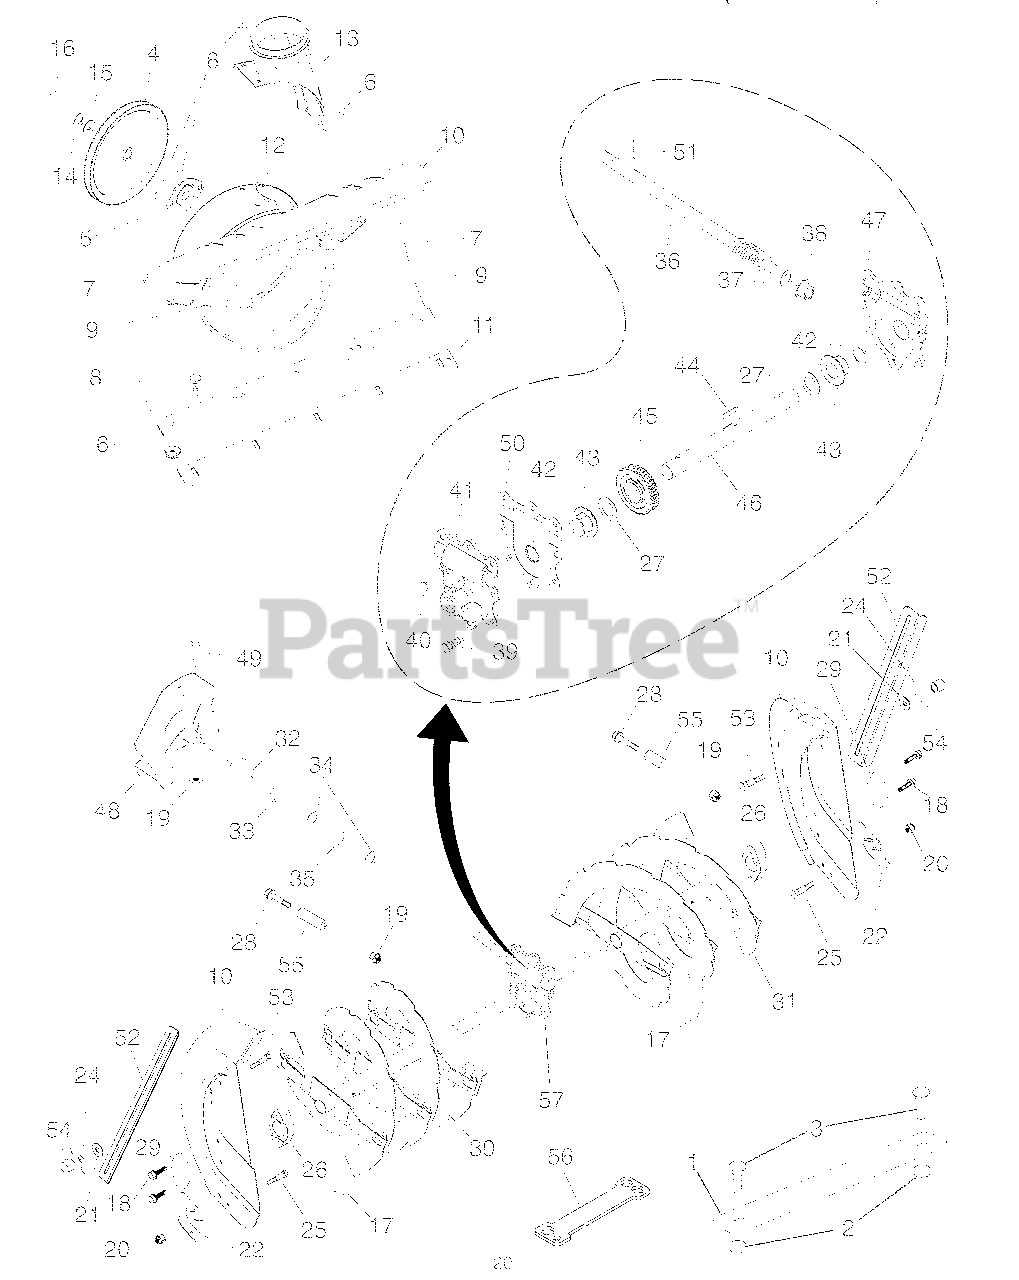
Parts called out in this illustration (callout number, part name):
1	Bar, Weight
2	Nut, Hex 5/16-18
3	Bolt, Carriage 5/16-18 x 1-1/4
4	Pulley, Impeller
5	Bearing Assembly, Flange
6	Nut, Hex Flange 5/16-18
7	Bolt, Flat Head, Carriage 5/16-18 x 5/8
8	Bolt, Carriage 5/16-1 8 x 5/8
9	Bolt
10	Housing, Auger
11	Bar, Scraper
12	Bracket, Corner Discharge
13	Base, Discharge Chute
14	Washer, Lock 5/16
15	Washer, Flat
16	Screw, Hex Head 5/16-18 x 3/4
17	Grease Fitting
18	Screw, Hex Head 5/16 x 1
19	Nut, Hex Lock 1/4-20
20	Nut, Hex Lock 5/16-18
21	Washer, Flat 5/16
22	Skid Plate, Heavy Duty
25	Bolt, Shoulder 1/4-20
26	Bearing Retainer, Plastic
27	Washer, Thrust, 1"
28	Bolt, Shear
30	Auger Assembly, RH
31	Auger Assembly, LH
33	Bushing, Flange 3/4
34	Washer, Thrust 3/4
35	Bearing, Thrust 3/4
36	Shaft, Impeller
37	Washer, Thrust 5/8
38	Bushing, Flange 5/8
39	Screw, Hex Head 5/16-18 x 3/4
40	Plug, Case
41	Housing, Gearbox, RH
42	Seal, Oil
43	Bushing, Flange, 1"
44	Key, Square 1/4 x 1/4 x 7/8
45	Gear, Worm
46	Shaft, Auger
47	Housing, Gearbox, LH
48	Impeller Assembly
49	Screw, Hex Head 1/4-20 x 1-5/8
50	Gasket, Gearbox
51	Pin, Roll 3/16 x 1-1/8
52	Bar, Drift Cutter
53	Bolt
56	Multi-Wrench
57	Gearbox Assembly
